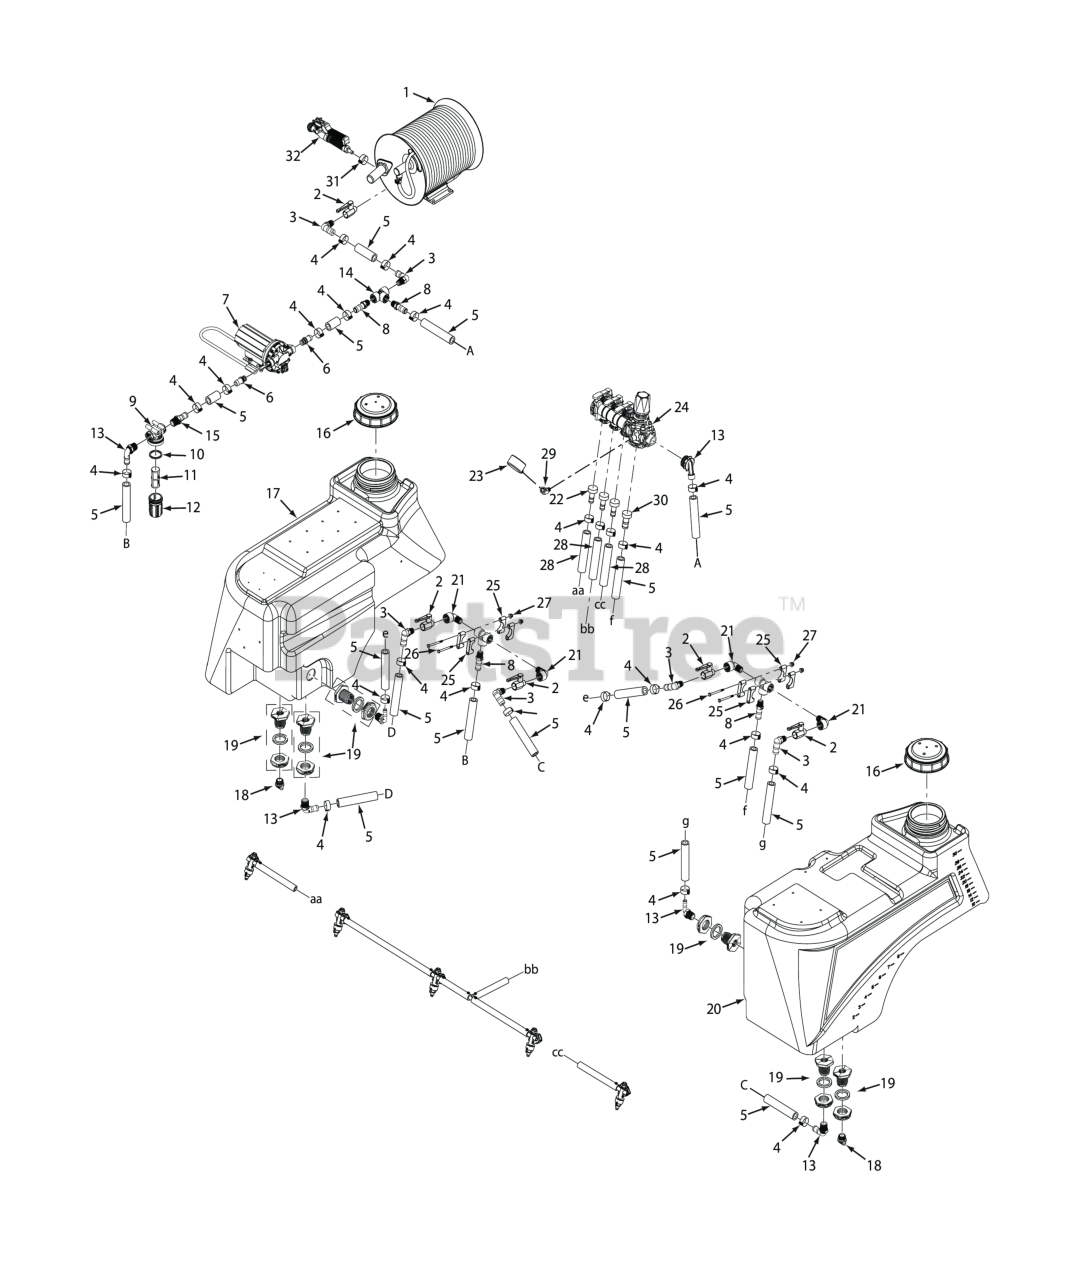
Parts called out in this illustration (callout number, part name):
1	Hose Reel Assy
2	Valve, Ball 1/2" NPT
3	Fitting, 90 Deg.1/2 - 14 NPT X 3/4" Hose
4	CLAMP, WORM DRIVE
5	Hose, 3/4" EPDM ( Order by the inch)
6	Fitting, 3/4" O-ring
7	Pump, 12V Electric
8	Hose Barb, 1/2" NPT X 3/4" Hose
9	Strainer Head
10	Gasket
11	Screen
13	Fitting, 90 Deg. 3/4 - 14 NPT x 3/4" Hose
14	Tee Fitting, 1/2 NPT
15	Hose Barb, 3/4 NPT x 3/4" Hose
16	Cap, Sprayer
17	Tank Assy, RH
18	Drain Plug, 3/4"
19	Fitting, 3/4" NPT
20	Tank Assy, LH
21	Fitting, Street Elbow 90 Deg. 1/2"
22	Fitting, Valve
23	Pressure Gauge
24	Valve Assy (Incl.
25	Mounting Bracket, Valve Assy
26	Bolt, 1/4 - 20 x 2.75 - Stainless Steel
27	Locknut, 1/4 - 20 Flg. Elastic Stop - Stainless Steel
28	Hose, 1/2" EPDM (order by the inch)
29	Fitting, 45 Degree 1/4 NPT
30	Fitting, Valve
31	Clamp, .69" Max. / .25" Min. Dia.
32	Sprayer Gun
